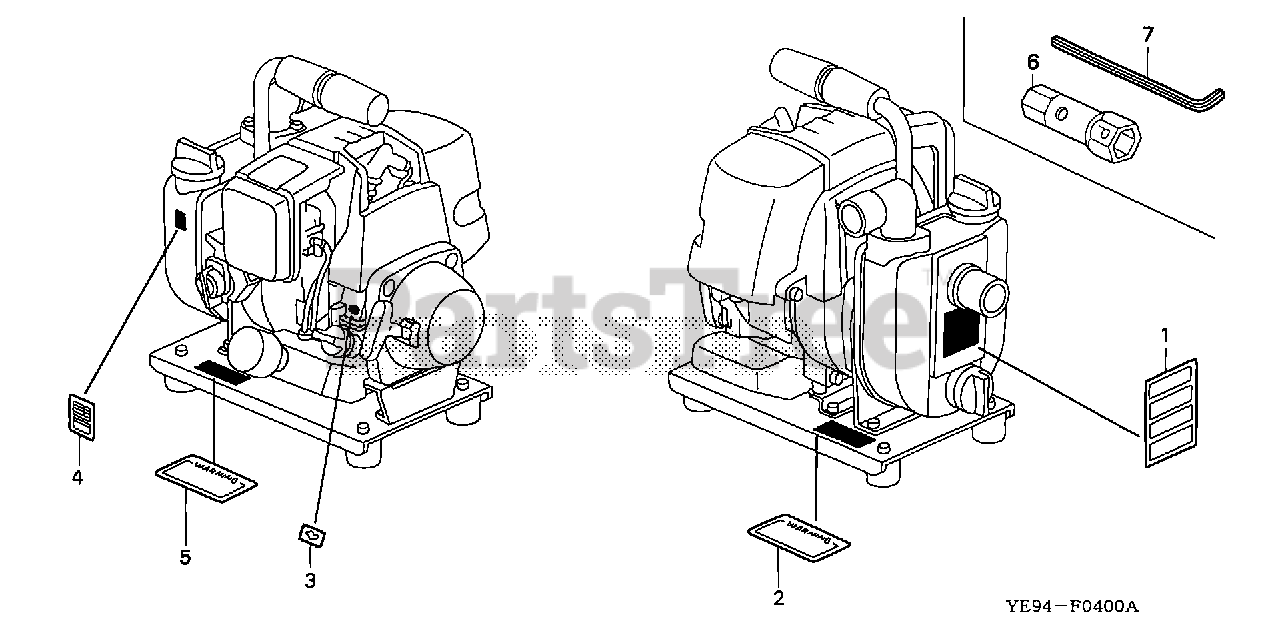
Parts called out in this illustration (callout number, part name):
1	MARK, CAUTION (PUMP)
2	LABEL, PUMP WARNING
2	LABEL, PUMP WARNING (ENGLISH)
3	MARK, OIL CAUTION
4	LABEL, CAUTION (PUMP)
